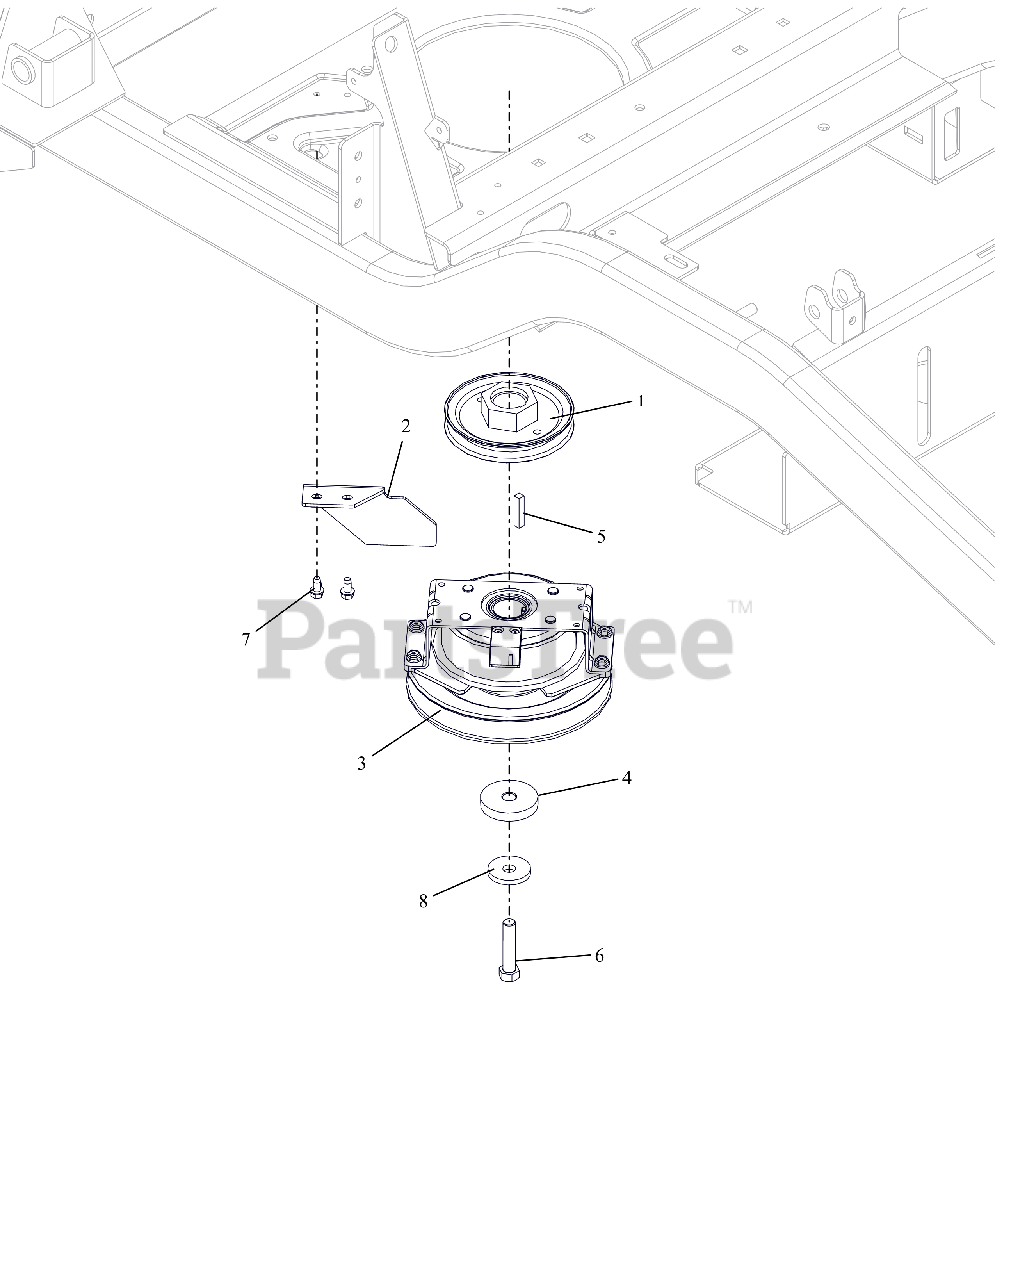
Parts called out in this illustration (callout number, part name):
1	WLDMT,PULLEY-4.50ODX1.127
2	BRKT, CLUTCH STOP HD
3	CLUTCH, OGURA DBLS SPRG 1.13"
4	SPACER, .474/.459X2.00X.350
5	KEY-SQ .25 X 1.25 X .25 SAE
6	BLT, HEX .44-20X2.00 G8 ZCC NT
7	SCR-TAP .25-20X.50 HWH ZCC
8	WASHER, 7/16" SPRING DISK
